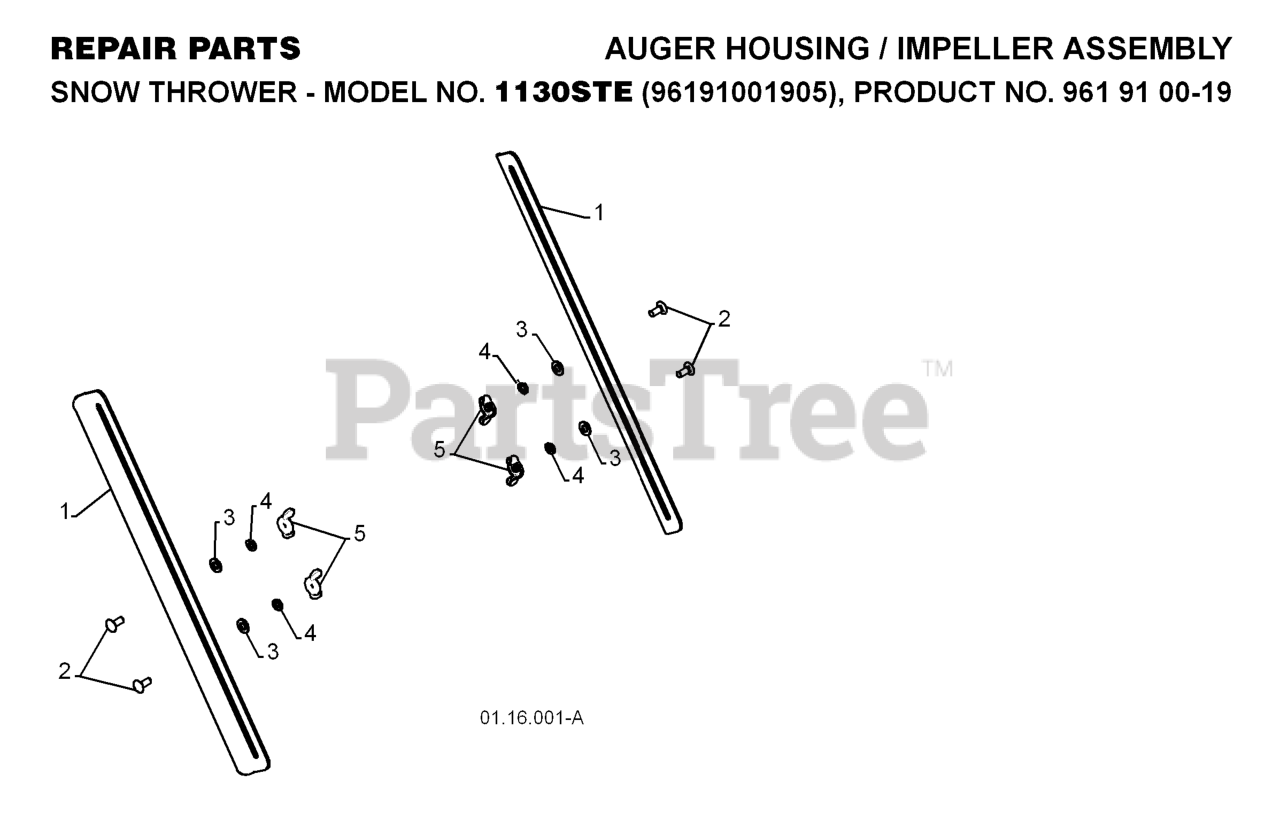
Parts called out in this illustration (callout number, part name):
1	DRIFT CUTTER BAR
2	BOLT
3	WASHER, NYLON FRICTION
4	WASHER.LOCK.HVY.HLCL.SPR.5/16
5	NUT WING PM
